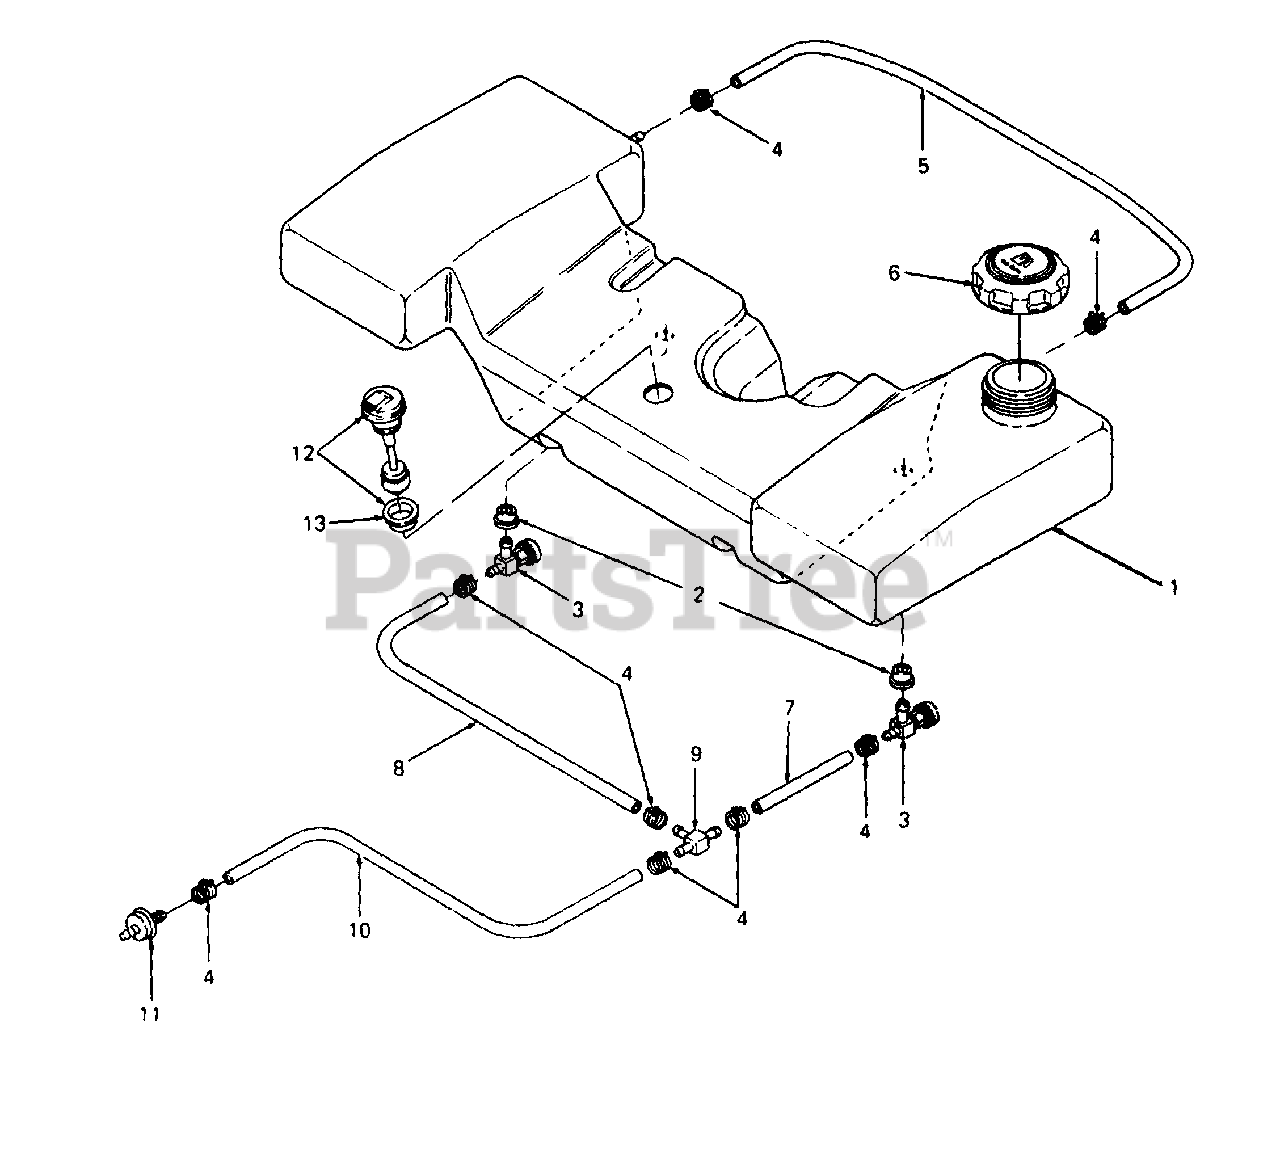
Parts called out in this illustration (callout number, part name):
1	Tank, Fuel
2	Bushing
3	Valve, Fuel Shutoff
4	Clamp, Hose
5	Line, Fuel - 24" Lg
6	Cap, Fuel
7	Line, Fuel - 5" Lg
8	Line, Fuel - 17" Lg
9	T-Fitting
10	Line, Fuel - 41" Lg
11	Filter, Fuel
12	Sensor, Low Fuel
13	Bushing, Rubber
